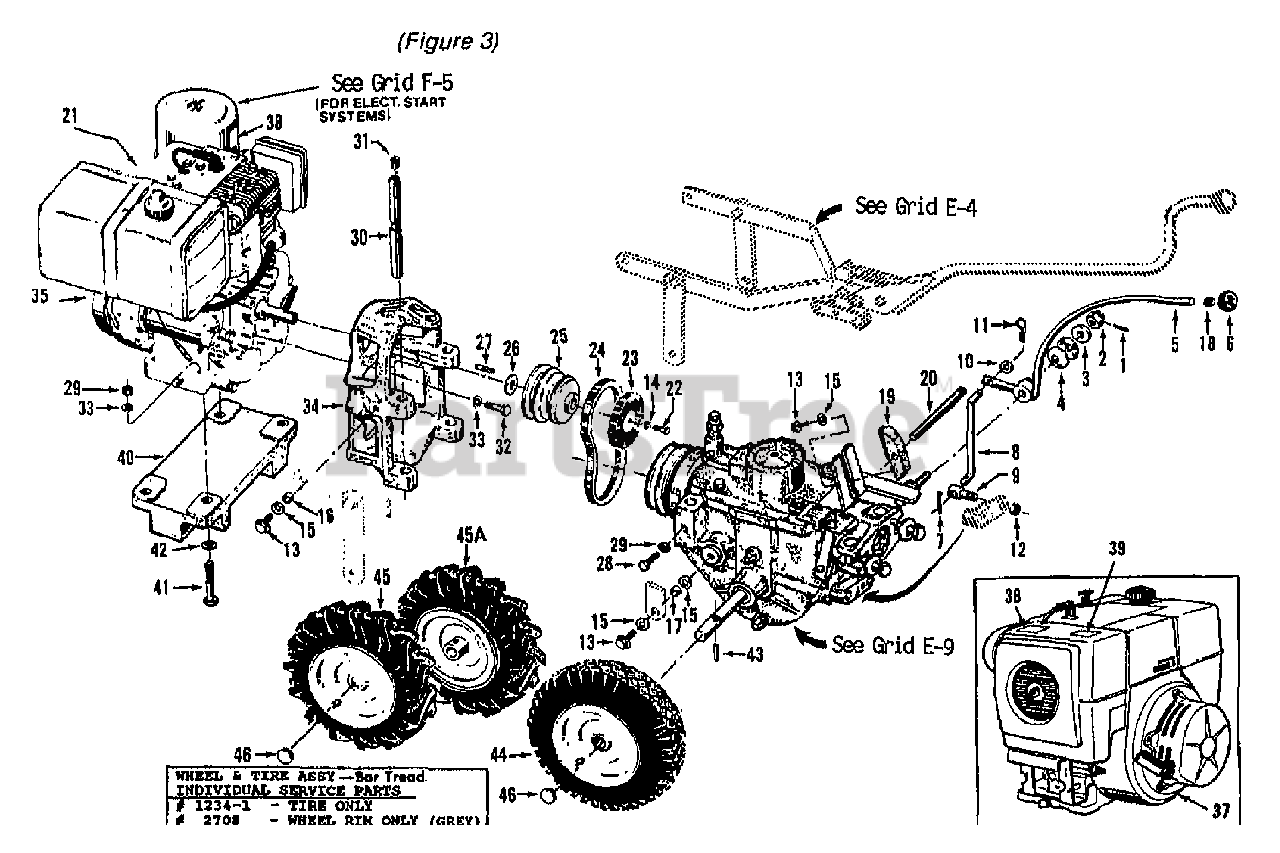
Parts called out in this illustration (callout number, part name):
1	PIN-SPRING .125 X 1
2	NUT-HEX 1/2-20 (CALL TECHNICAL SERVICE DEPARTMENT FOR TIGHTENING INSTRUCTIONS)
3	WASHER-# SHOULDER ZP (SHOULDER FACES DISC WASHERS)
4	WASHER-# 1.97X1X.118 (CONCAVE SURFACES FACE EACH OTHER)
5	LVR-W/KNOB - WHEEL SPEED (INCLUDES REF.#6&18)
6	KNOB-WHEEL SPEED HORSE
7	PIN-COTTER .094X1.0
8	ROD-CONNECTING
10	WASHER-FLAT 5/16 SAE
11	PIN-CLIP .08
12	NUT-H/LK 5/16-18
13	SCR-HFLK 3/8-16X1.00 ZP
14	WASHER-LK .375 @ DEPL
15	WASHER-FLAT 3/8 SAE
16	BUSHING-.5X.375X.325
17	BUSHING-.5X.375X.3
18	RING-TOLERANCE .5325 ID
19	KIT-ADJ BLOCK 4 SP (INCL. 13,15,20)
20	BAR-ADJUST
21	DECAL-STARTING STABIL (FOR B & S ENGINE)
22	SCR-HH 3/8-24X1.5 G5
23	KIT-ADJ BLOCK/REV DISC
23	DISC-REV
24	BELT-V
25	PULLEY-ENG MACH
26	SHIM-1.0X.7656X.062
26	SHIM-1.0X.7656X.031
27	KEY-.188 SQ X 2.33
28	SCR-HH 5/16-18X1.0 G5 ZP
29	NUT-HEX 5/16-18 ZP
30	BAR-ENG MTG W/CAP PLUG
31	PLUG-CAP (RED)
32	BOLT-HH 5/16-24X1.125 G5 ZP
33	WASHER-LK .312 ZP
34	MOUNT-MOTOR HSE OPC PNT
35	7 HP BRIGGS & STRATTON ENGINE - RECOIL START
35	7 HP BRIGGS & STRATTON ENGINE - ELECTRIC START
37	8 HP KOHLER MAGNUM ENGINE - RECOIL START
37	8 HP KOHLER MAGNUM ENGINE - ELECTRIC START
38	DECAL-HOT SURFACE
39	DECAL-STABIL STARTING
40	WEIGHT-ENG ECONO PNT
41	SCR-HH 5/16-18X2.25 G5ZP
42	SPACER-.88X.385X.09 ZP
43	PIN-SPIROL .313 X 1.5
44	ASSM-STD TIRE
45	TIRE-LT BT GARDEN TRAC (WHITE)
45	ASSM-TIRE&WHEEL LH GRAY
45A	TIRE-RT BT GARDEN TRAC (WHITE)
45A	ASSM-TIRE&WHEEL RH GRAY
46	CAP-HUB BLK PLASTIC
